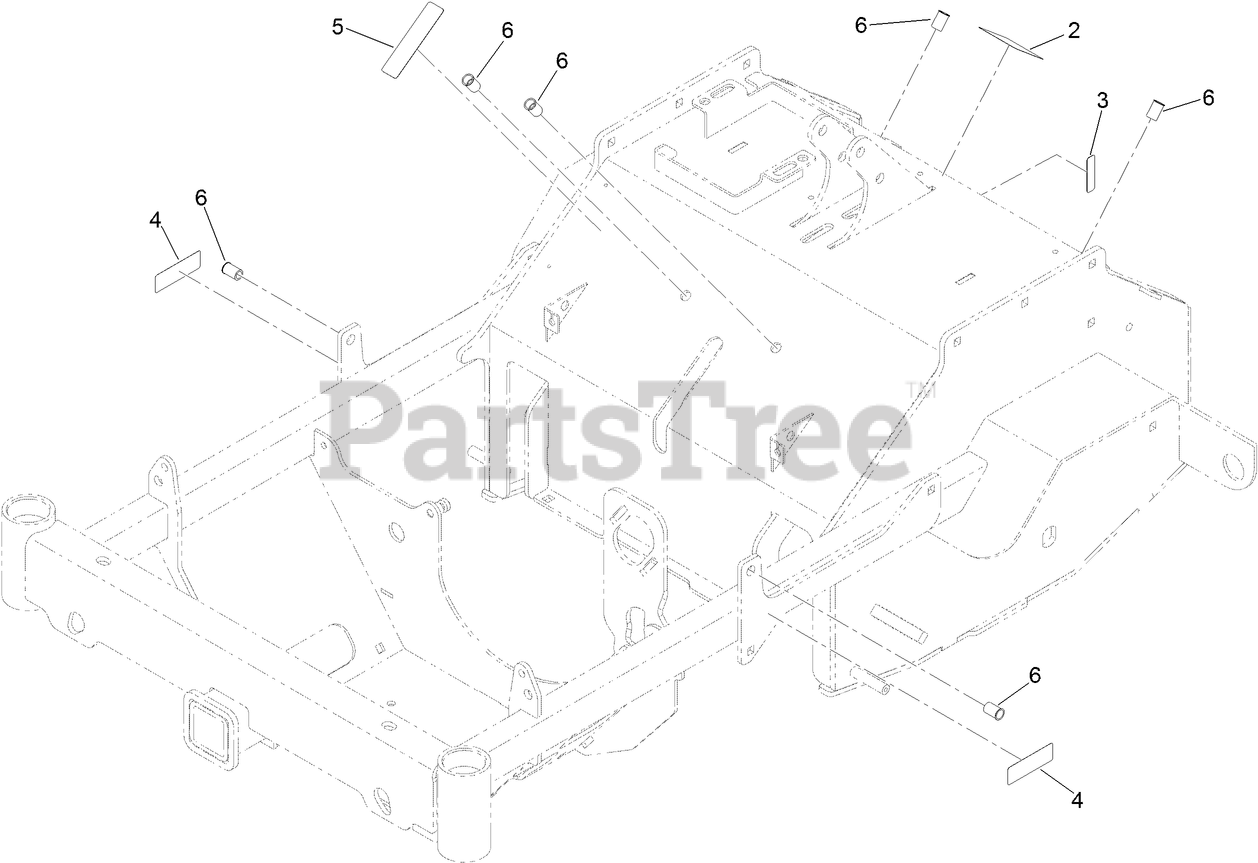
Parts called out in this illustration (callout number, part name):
2	DECAL-WARNING
3	DECAL-WARNING
4	DECAL-DANGER
5	DECAL-ARRESTOR, SPARK
6	NUT-CLINCH
